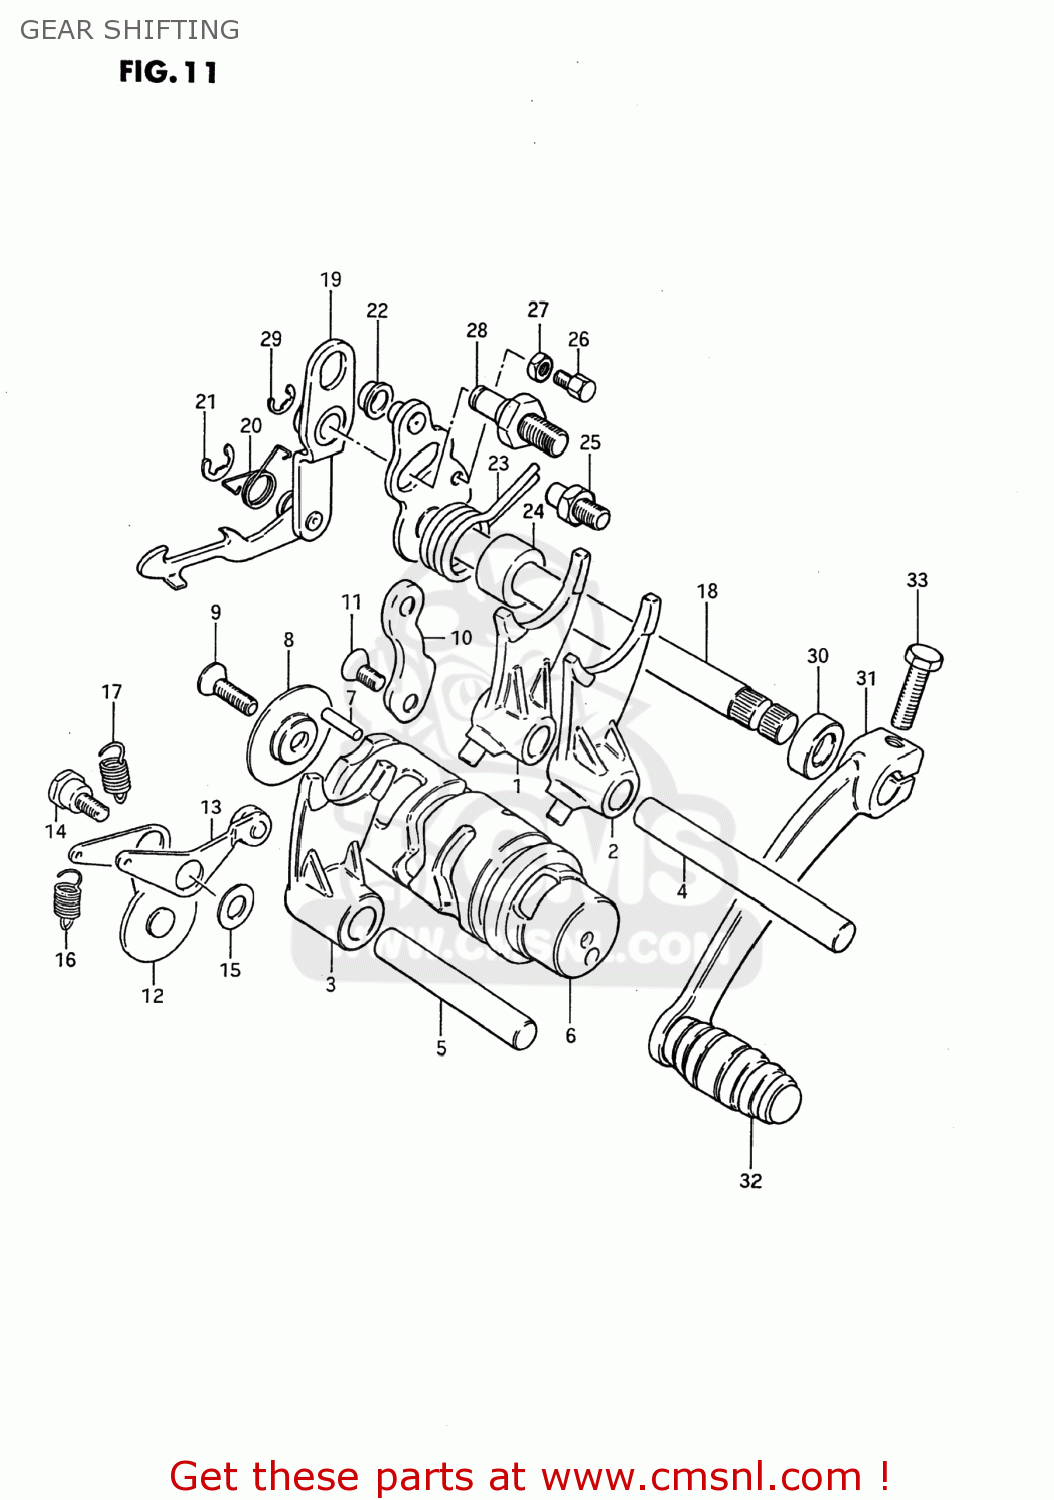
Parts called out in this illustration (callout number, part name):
1	FORK,GEAR SHIFT NO.1
2	FORK,GEAR SHIFT NO.2
3	FORK,GEAR SHIFT NO.2
4	SHAFT,GEAR SHIFT FORK
5	SHAFT,GEAR SHIFT FORK
6	CAM,GEAR SHIFT
7	PIN
8	RETAINER,GEAR SHIFT CAM DR PIN
9	SCREW
10	GUIDE,GEAR SHIFT CAM
11	SCREW
12	STOPPER,GEAR SHIFT CAM
13	STOPPER,GEAR SHIFT CAM NEUTRAL
14	BOLT(6X18.3)
15	WASHER
16	SPRING
17	SPRING
18	SHAFT,GEAR SHIFT
19	PAWL,GEAR SHIFT
20	SPRING
21	E RING
22	SPACER(7X10X5)
23	SPRING
24	SPACER(12X20X15.3)
25	STOPPER,GEAR SHIFT CAM
26	BOLT,GEAR SHAFT RETURN SPR SET
27	NUT
28	STOPPER,GEAR SHIFT CAM
29	E.RING
30	OIL SEAL
31	LEVER ASSY,GEAR SHIFT
32	RUBBER,GEAR SHIFT PEDAL
33	BOLT
